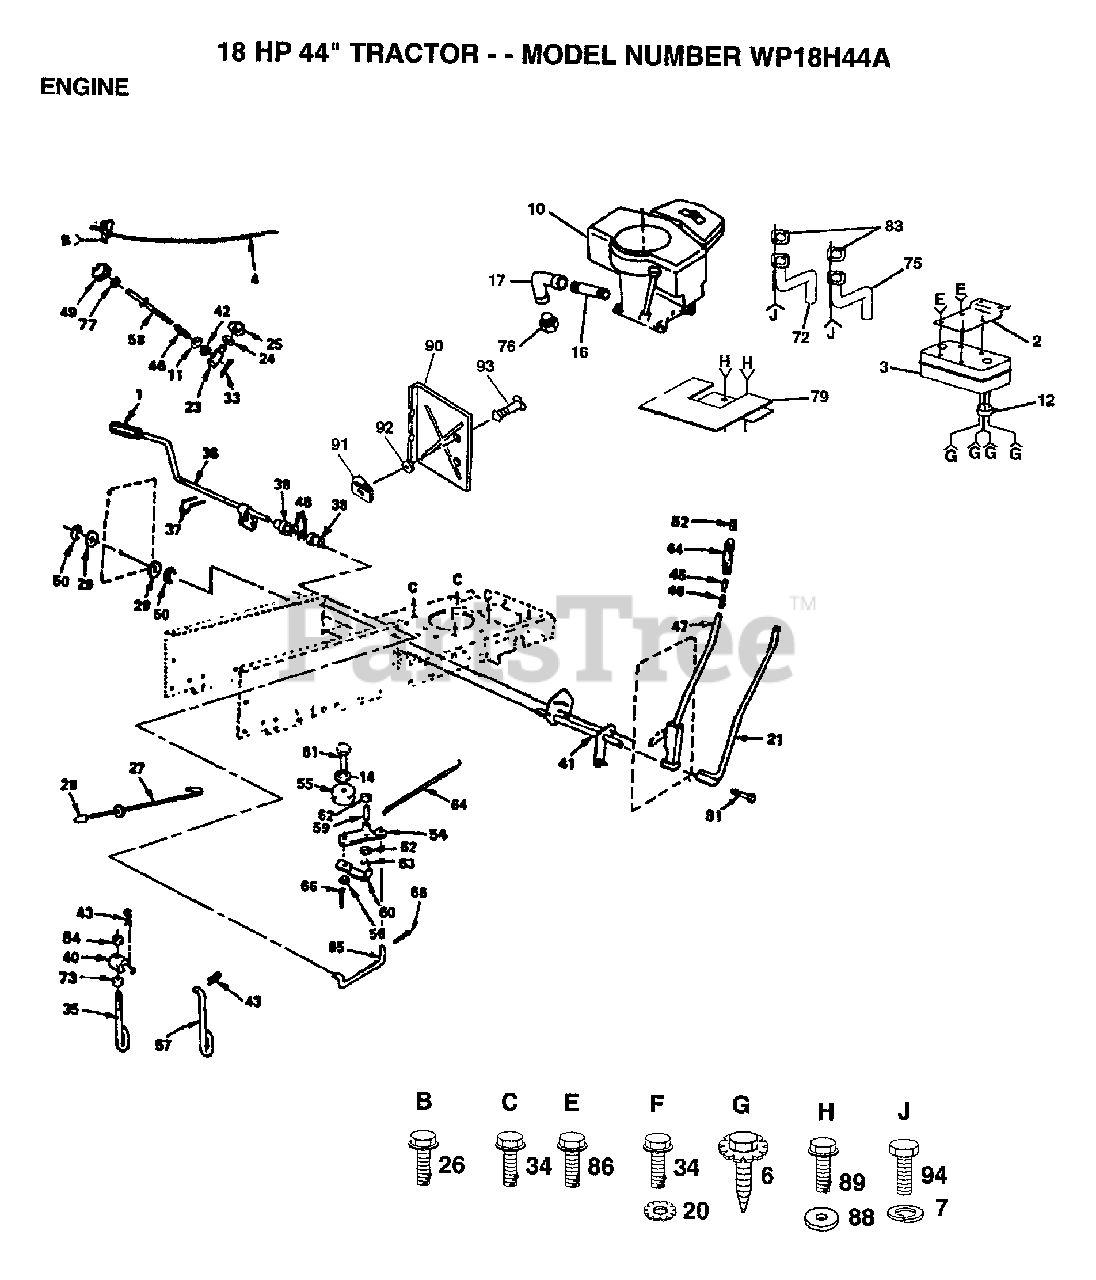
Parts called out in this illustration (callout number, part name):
1	PEDAL COVER T
2	BRACKET MUFFLER
4	THROTTLE CONTROL
7	LOCKWASHER
11	WASHER
12	DEFLECTOR.222573
14	WASHER
16	PIPE NIPPLE LT
17	ELBOW
20	LOCKWASHER
21	LEVER ROD LT
23	TRUNION LT
24	WASHER
25	KLIP RING
26	SCREW LT
27	BRAKE PARK ROD
28	PLUNGER CAP T
29	WASHER
34	SCREW LT
35	PIVOT PIN T
38	NYLON BEARING
41	LIFT SHAFT ASM
42	NUT T
44	GRIP
46	SPRING T
48	WASHER LT
50	E-RING
54	ARM IDLER
57	LIFT LINK LT
58	ROD LIFT LT
59	"LY, BEARING"
60	RETAIN BELT
62	WASHER LT
63	KLIP RING
64	"SPRING, RETURN LT"
65	"LINK, CLUTCH T"
66	COTTER PIN
73	NUT
77	NUT
81	"BOLT,HEX"
86	SCREW ST
88	WASHER
89	SCREW
90	HEAT SHIELD
91	RECEPTACLE LT
92	RETAINER LT
93	STUD.1/4.TURN
